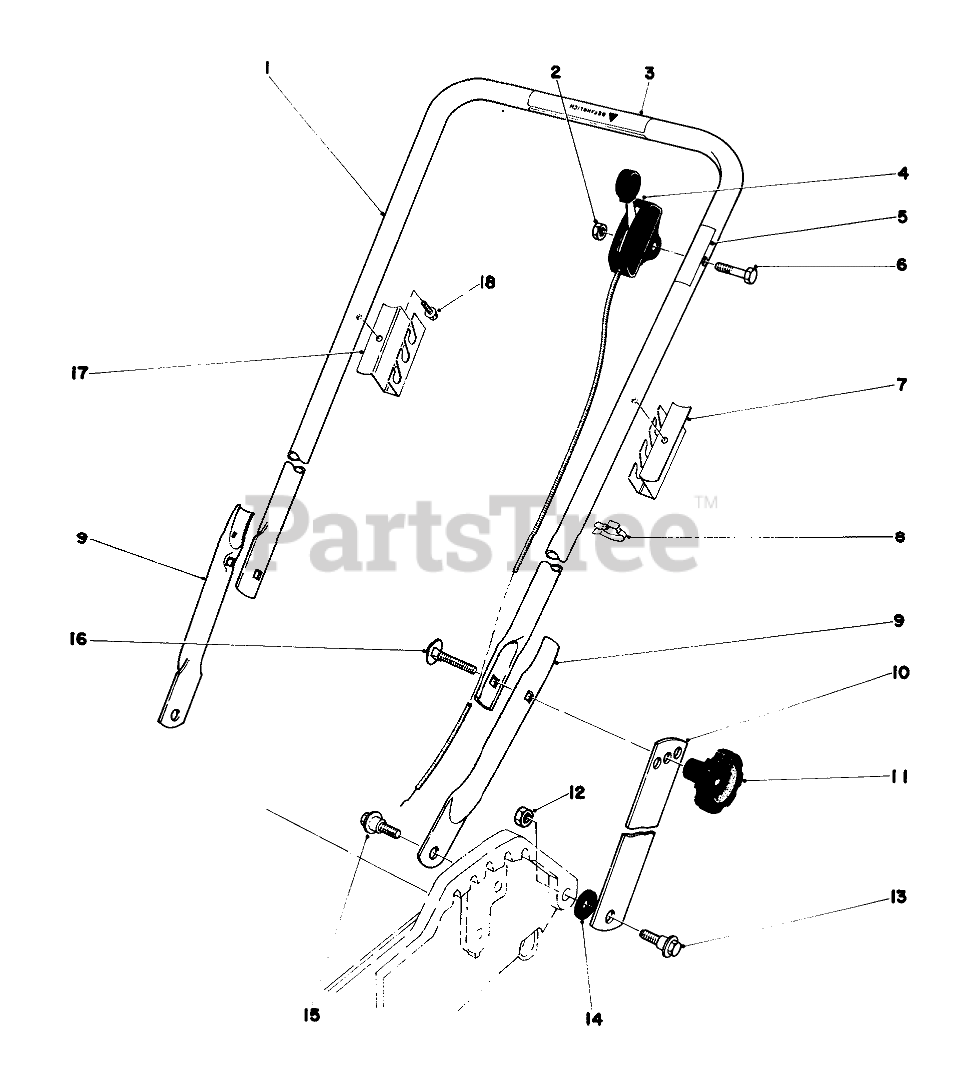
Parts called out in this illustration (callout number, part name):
1	Handle-Upper
2	NUT-LOCK
3	Decal Danger
4	Throttle Control
5	Decal-Throttle
6	SCREW-HH
7	SUPPORT BAG LH
8	BOWDEN CLIP
9	Hand-Lower
10	18" HANDLE LATCH
12	Nut
13	SCREW-SHOULDER
14	SPACER
15	SCREW-SHOULDER
16	SCREW-HANDLE
17	SUPPORT BAG RH
18	SCREW-HWHTF
